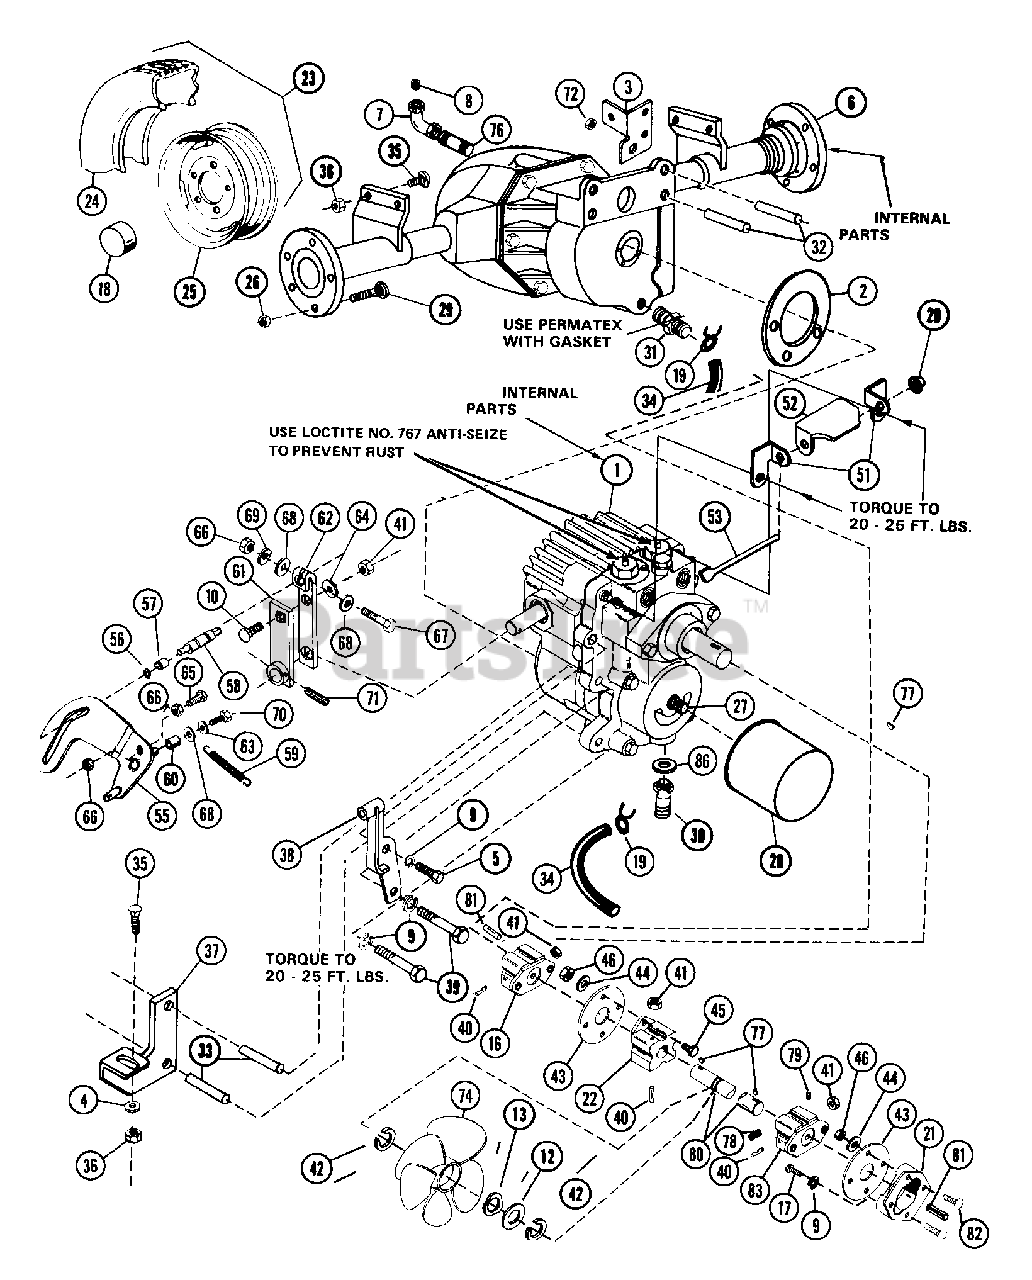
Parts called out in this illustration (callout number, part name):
1	SUNDSTRAND TRANSMISSION W/FILT
3	TORQUE BRACKET
4	WSHR-FL-STL .531X1.062X.095 PL
5	BLT-HEX .38-16X1.50 PL GR2
6	REAR AXLE AND SUPPORTS
7	ELBOW 1/2 X 90
8	PIPE PLUG
9	WSHR-LK .375X.094 MED PL
10	BLT-RDHDSQNK .38-16X1.0 GR5PL
12	WSHR-FL-STL .754X1.000X.032
13	SPRING WASHER
16	DRIVE HUB - HYDRO
17	@BLT-HEX .38-16X.88 PL GR2
18	REAR HUB CAP
19	HOSE CLAMP #15 .906/.968
20	PUSH NUT, .312
21	DRIVE HUB - FLYWHEEL SINGLE
21	DRIVE HUB - FLYWHEEL TWIN
22	DRIVE HUB
23	10.50 X 23 REAR TIRE ASSY.
26	NUT-LUG .437-20 YWZC
28	OIL FILTER
29	CARRIER LUG BOLT
30	CONNECTOR
31	CONNECTOR 3/4
32	SPACER .379X.625X3.480
33	SPACER .379X.625X3.298
34	HOSE .62X.91X8.00
35	BLT-RDHDSQNK .50-13X1.25GR5PL
36	NUT-LK-CROWN .50-13 GR C PL
37	BRACKET
38	CAM PIVOT BRACKET
39	BLT-HEX .38-16X5.00 PL GR2
40	LOCK STUD
41	NUT-LK TOP .375-16 GR C YWZC
42	RG-RTNG-EXT .750X.042
43	SPACER COUPLING
44	WSHR-FL-STL.344X.688X.065PL
45	BLT-HEX .31-18X.88 PL GR2
46	NUT-LK .312-18 GR A PL
51	SUPPORT
53	PIVOT ROD
56	RG-RTNG-EXT .312X.025
57	CAM ROLLER
58	PIN ECCENTRIC
59	SG-TENS .060X.75X2.81 WLD 6
63	WSHR-FL-STL .531X1.062X.095 PL
64	WSHR-FL-STL.406X.812X.065PL
65	BLT-HEX .25-20X1.00 GR2
66	NUT-HEX .250-20 PL
67	BLT-HEX .25-20X2.00 PL GR5
68	WSHR-FL-STL.281X.62X.065 PL
69	WSHR-LK .250X.077 HVY PL
70	BLT-SERHFWH .25-20X.50 PL
71	PIN-ROLL .250X1.38
72	NUT-LK-CTR .312-24 PL
76	PIPE NIPPLE 1/2 X 2
77	KEY-WDRF .188X.75X.313 SAE 9
78	LOCK STUD
79	SCR-SET .38-16X.50 SKHCUP OH
80	DRIVE SHAFT - HYDRO SINGLE
80	DRIVE SHAFT - HYDRO TWIN
81	PIN-GRV .313X.75 TP D
82	BLT-SERRDHD SL .31-18X.87 PL
83	DRIVE HUB
83	DRIVE HUB - TWIN SHAFT
84	LOCK STUD
86	O-RING .250X.943X.103
87	NUT-HEX .375-16
